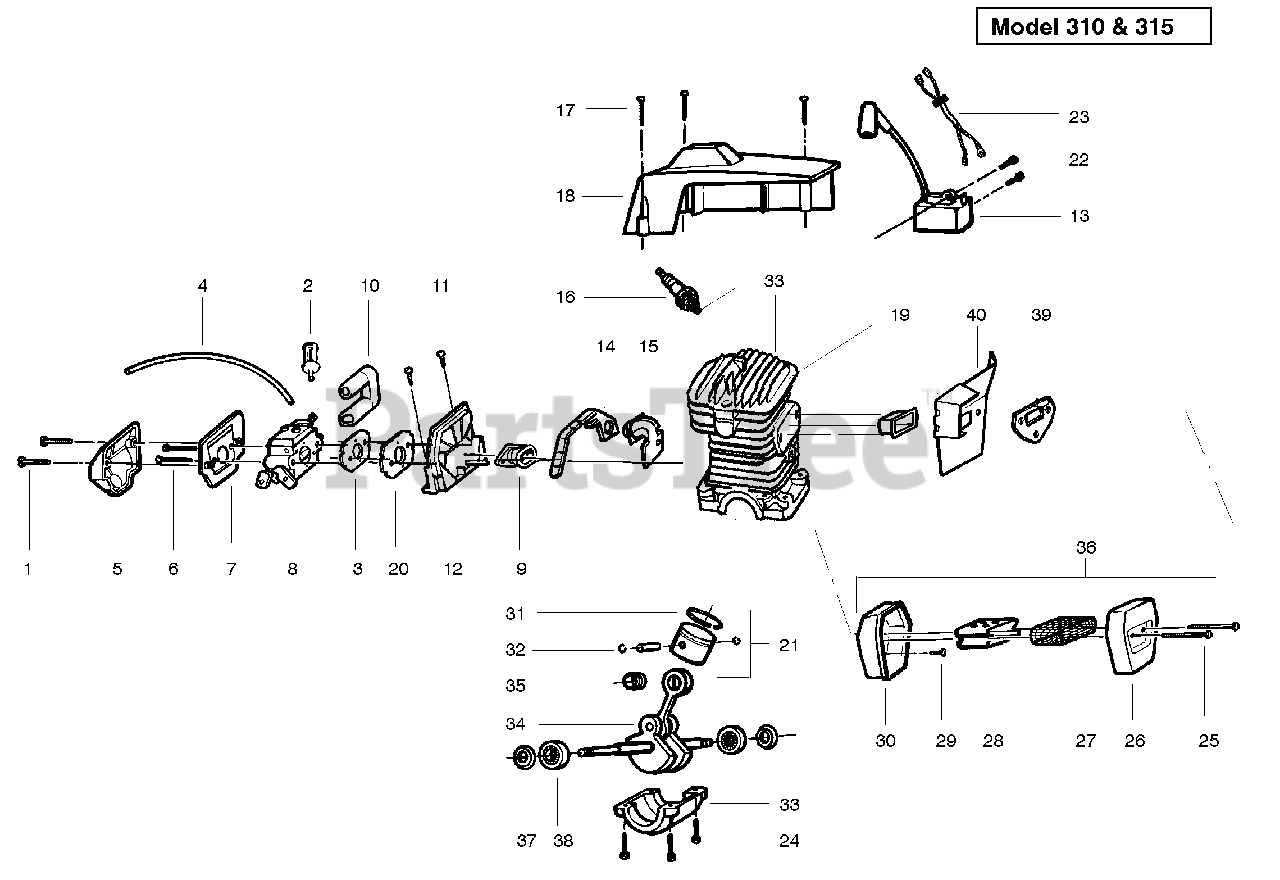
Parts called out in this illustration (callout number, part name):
2	Fuel Pick-up
3	Carburetor Gasket
4	Fuel Line
5	Air Filter (Top)
7	Air Filter (Bottom)
8	Carburetor WT-285
9	Intake Boot
10	Carb. Grommet
11	Screw
12	Carb. Adaptor
13	Ignition Module
14	Turbo Clean Seal
15	Turbo Air Cleaner Ass'y.
16	Spark Plug (CJ-7Y)
18	Cylinder Shield
19	Heat Insulator
20	Carburetor Plate
21	Piston Kit
23	Switch Wire Ass'y.
25	Muffler Bolt
26	Muffler Cover
27	Spark Screen
28	Diffuser
30	Muffler Body
31	Piston Ring
32	Piston Pin Retainer
33	C'case&Cylinder Assy
34	C'shaft & Rod Ass'y.
35	Piston Pin Bearing
36	Muffler Kit
37	C'shaft Seal
38	C'shaft Bearing
39	Muffler Gasket
40	Muffler Plate
